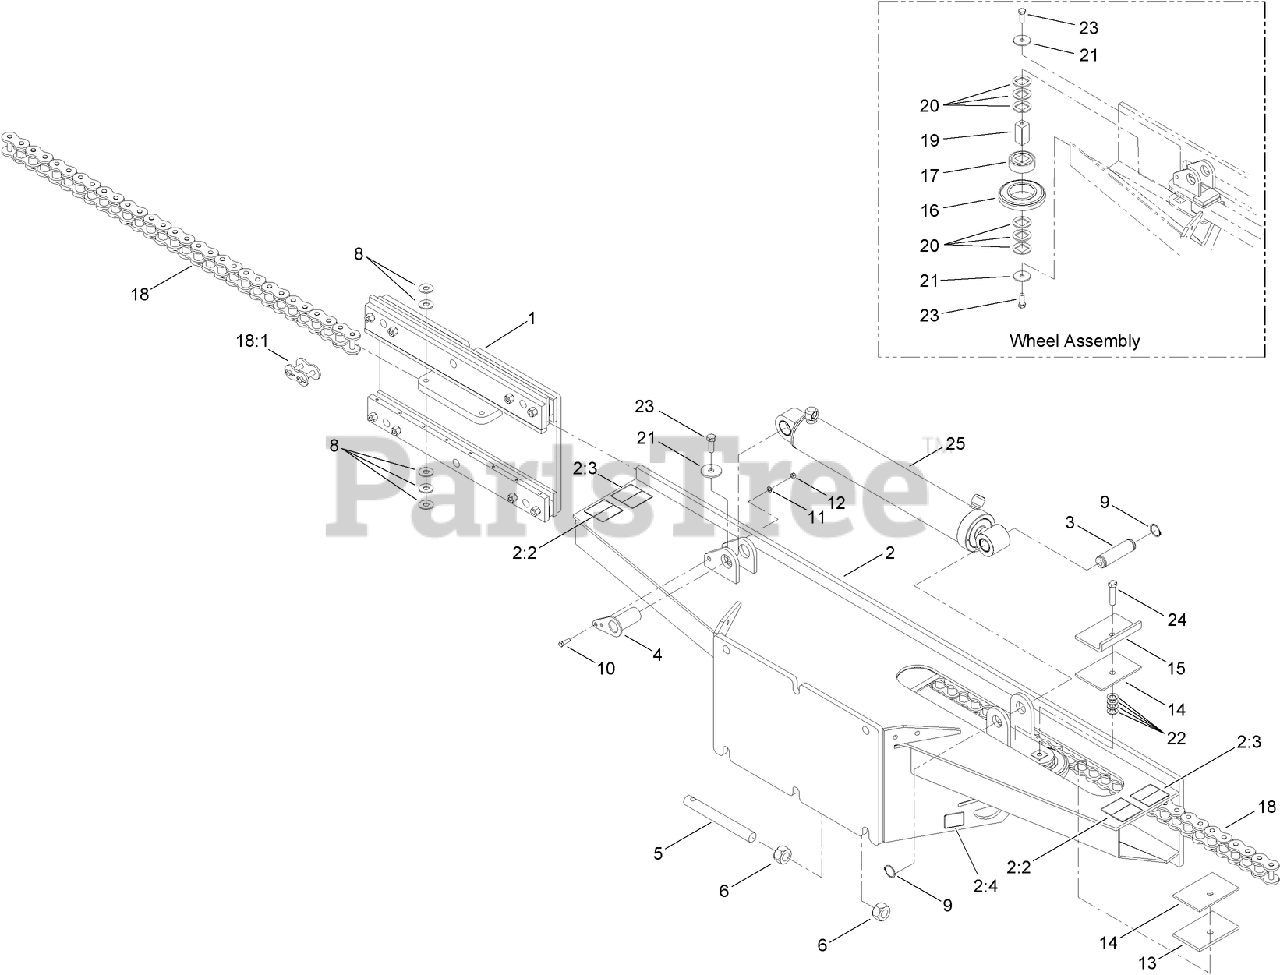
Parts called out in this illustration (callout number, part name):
1	SLIDE MOUNT ASM
2	SIDE SHIFT ASM
2:2	DECAL-WARNING, CRUSHING
2:3	DECAL-DANGER, CRUSHING
2:4	DECAL-TIE DOWN
3	PIN-PIVOT
4	PIN-BOOM (CYLINDER)
5	ROD-THREADED
6	NUT-HEX
8	WASHER-FLAT
9	RING-RETAINING, EXTERNAL
10	SCREW-HH
11	WASHER-LOCK
12	NUT-HEX
13	PLATE-SLIDE
14	SHEET-WEAR STRIP
15	PLATE-SLIDE, UPPER
16	WHEEL-BOOM END, IDLER
17	BEARING
18	CHAIN ASM
18:1	LINK-MASTER
19	BAR-AXLE, ROLLER
20	WASHER
22	WASHER-FLAT
23	SCREW-HH
24	SCREW-HH
25	HYD CYLINDER ASM
